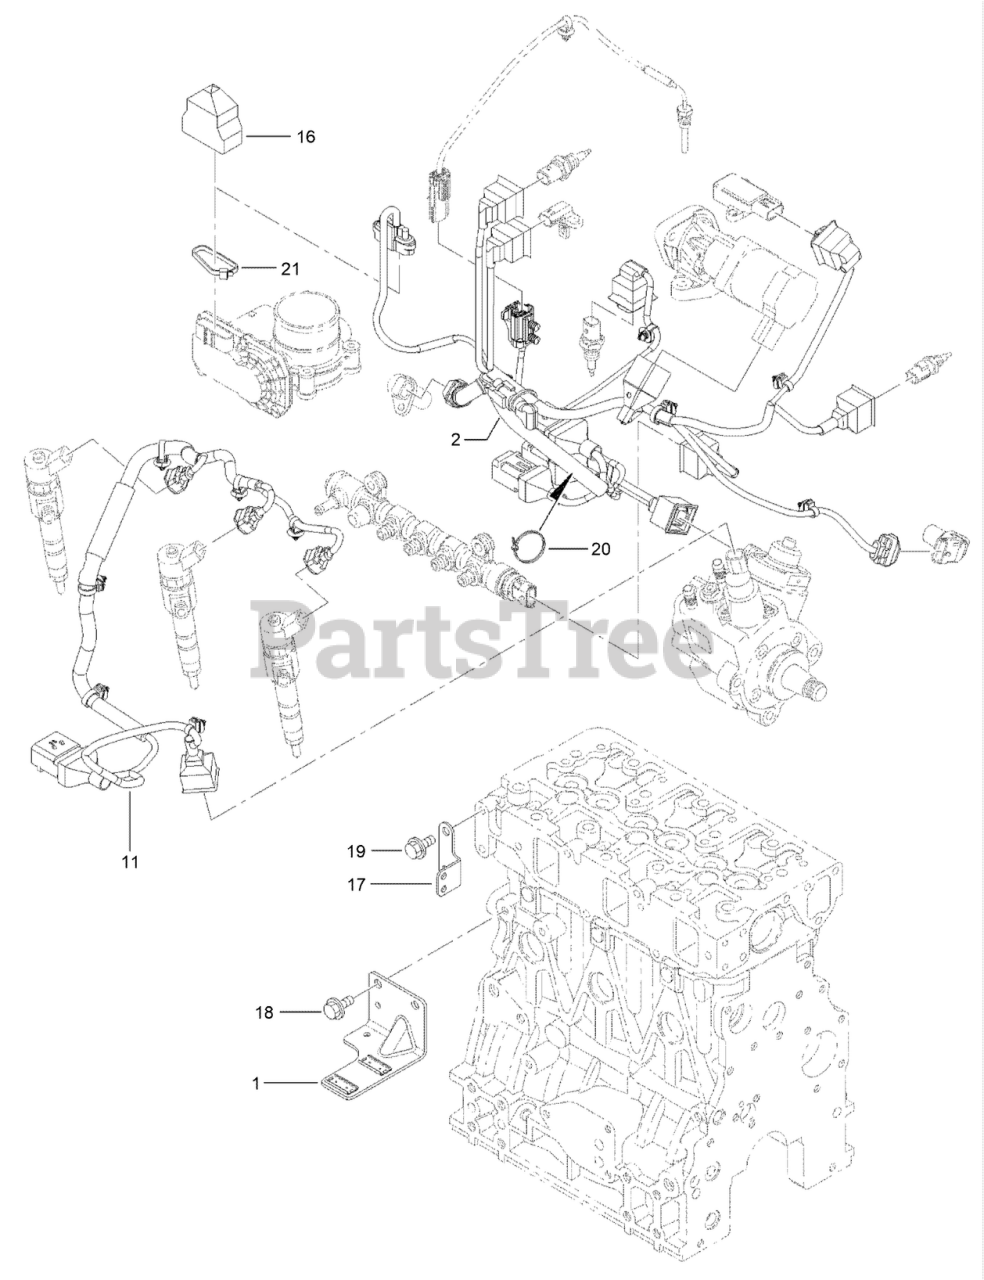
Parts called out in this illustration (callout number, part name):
1	BRACKET-CONNECTOR
2	HARNESS
11	HARNESS
16	BOOT-CAP
17	BRACKET-HARNESS
